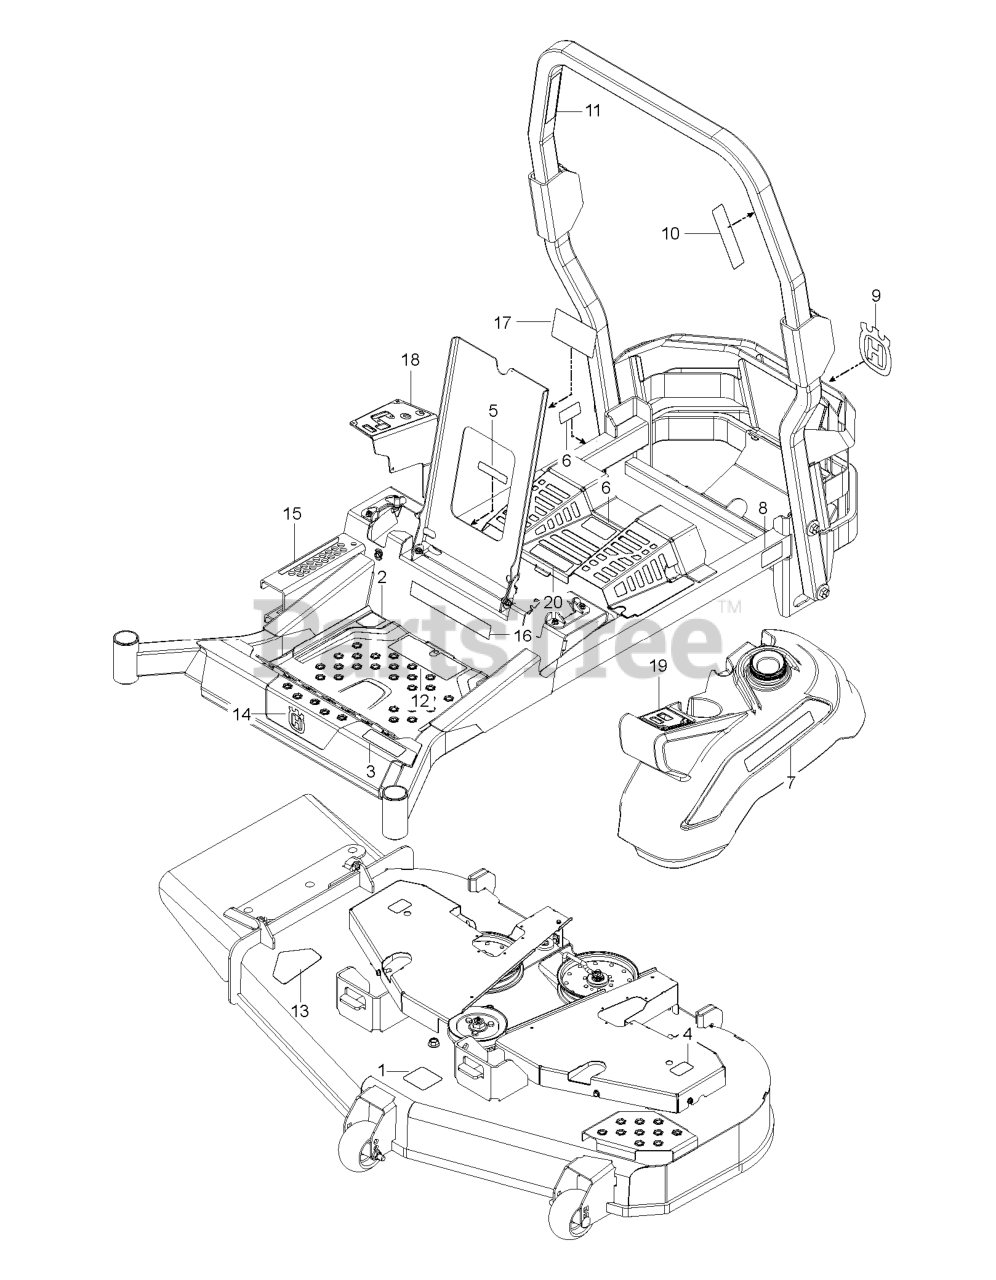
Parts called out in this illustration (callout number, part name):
1	DECAL, BELT ROUTING
2	DECAL.ZTR.SADLE.WARN.PZ500.ENG
3	DECAL.ZTR.PZ500SERIES.MODEL.Z5
4	DECAL.DECK.6MIL.EURO.NOSTEP
5	EURO DECAL-BATTERY WARNIN6
6	DECAL, BELT DRIVE
7	DECAL.HUSQVARNA.210MM
8	DECAL.NOISE.LEVEL.105DB/CE.EAC
9	DECAL, CROWN H, 110MM
10	DECAL ROPS DECAL DECAL.ROPS.PZ
11	DECAL, ROPS, WARNING
12	DECAL ZTR WARNING DECAL DECAL.
13	DECAL, DECK DEFLECTOR, WARNING
14	DECAL.BADGE.55MM.CROWNH.HUSQ
15	DECAL.PZ500.DECKLIFT.HUSQ
16	DECAL.ZTR.SADDLE.COMM.PZ500
17	DECAL.PZ500.MAINTANCE/SVC.2018
18	DECALZTR.CONTROLPANEL.PZ500.RH
19	DECAL.ZTR.CONTROLPANL.PZ500.LH
20	DECAL.ZTR.TRANCOVER.WARN.PZ500
